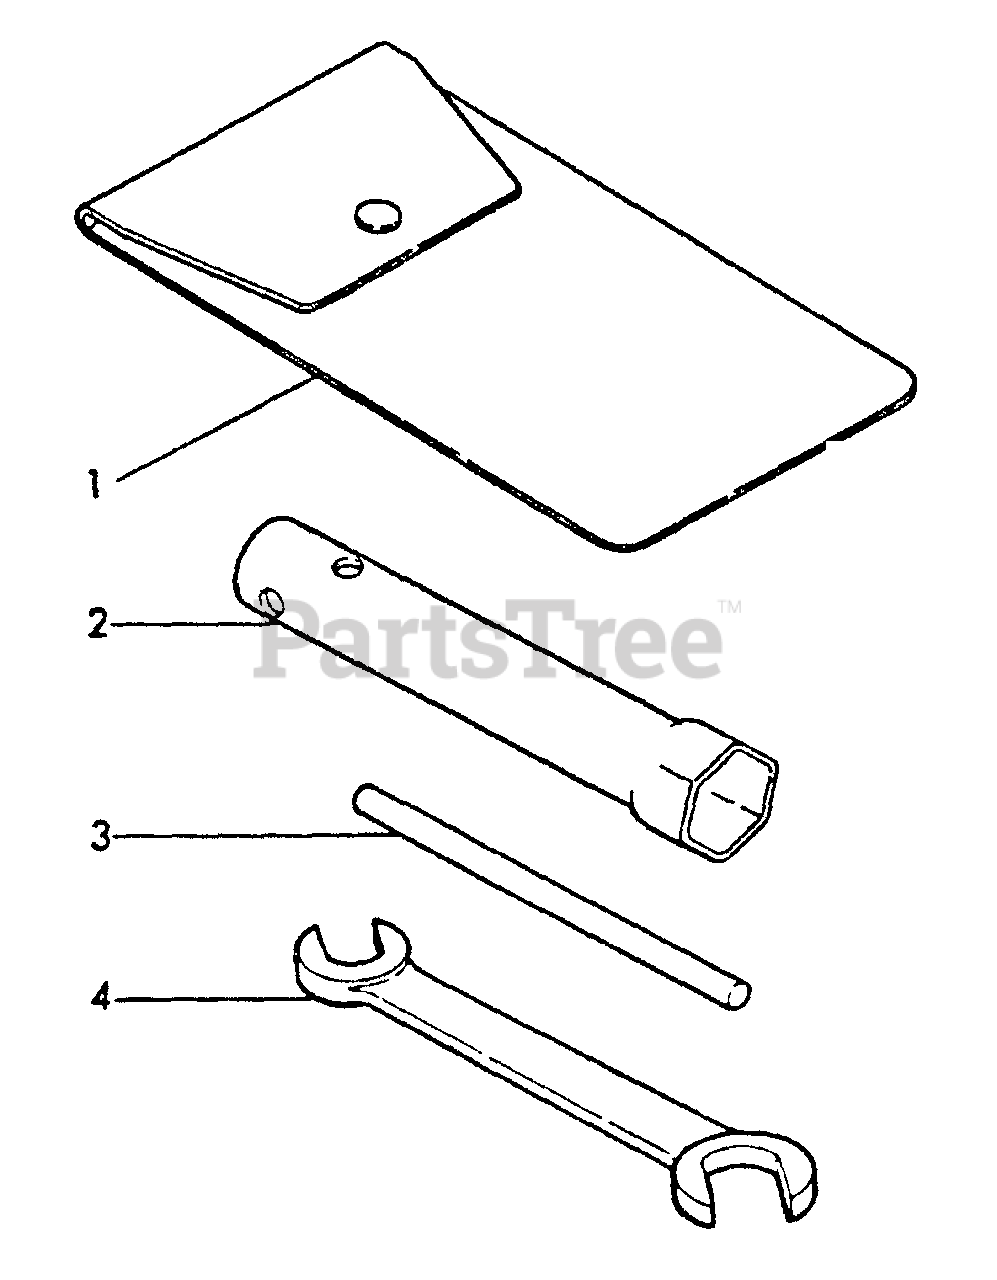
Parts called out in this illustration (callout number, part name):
1	BAG, TOOL
2	SOCKET WRENCH - 21mm
3	BAR
4	SPANNER - 10X12mm
